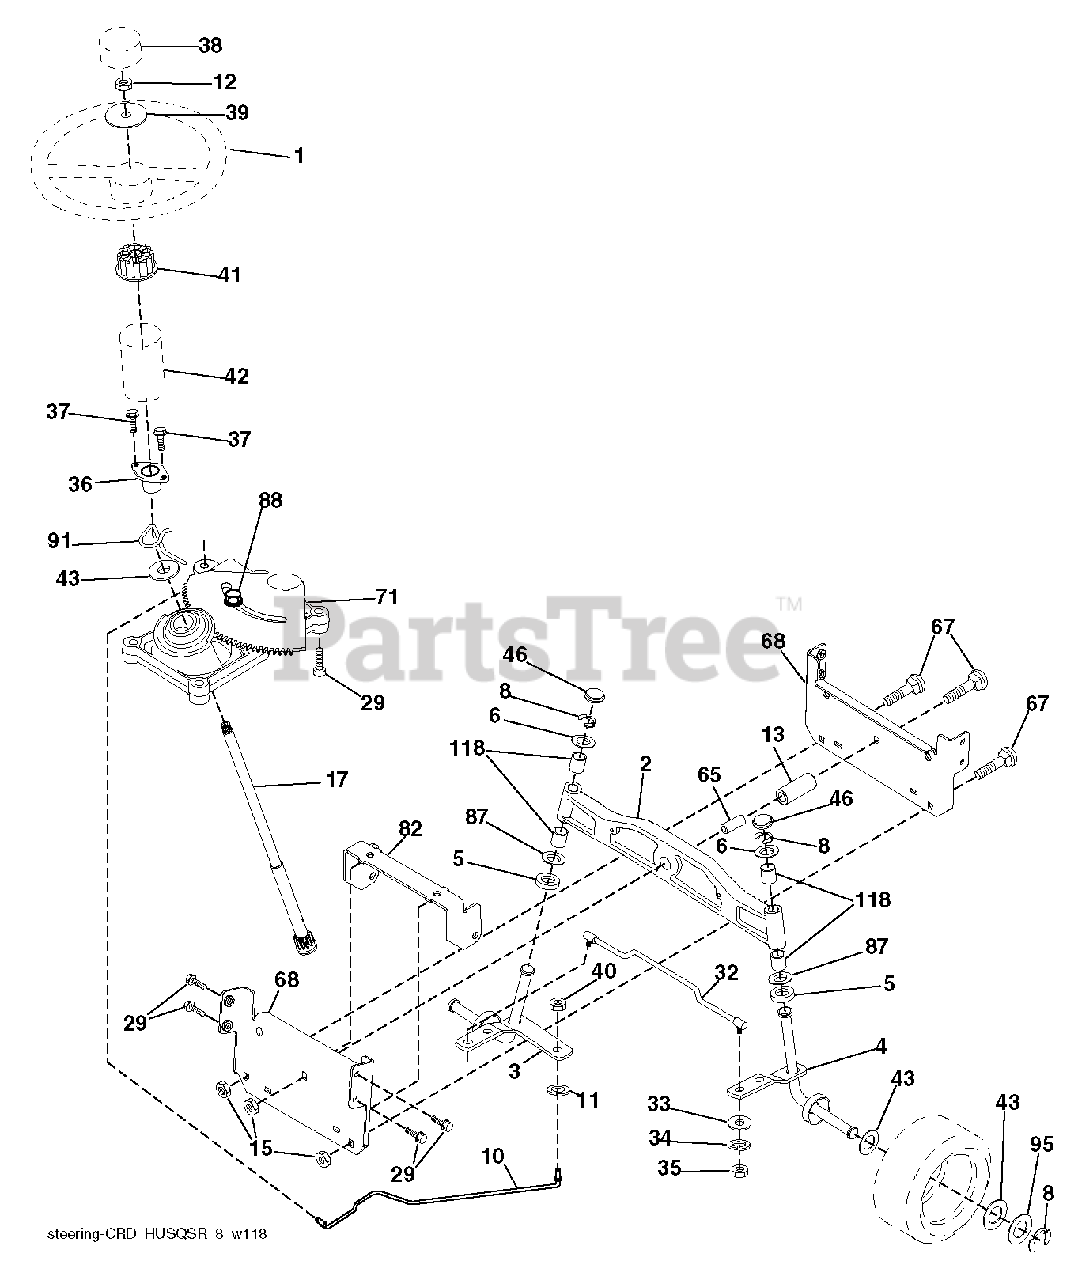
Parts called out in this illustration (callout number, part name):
1	WHEEL.STEERING.STDSRR.BLK/OV
2	AXLE.ASM.LT.CAST.LGHTWGHT
3	SPINDLE.ASM.LH.15"TIRES
4	SPINDLE.ASM.RH.15"TIRES
8	RING CLIP
10	DRAGLINK.15".TIRES.2001
11	WASHER, LOCK 3/8
12	NUT.HEX.1/2-20
13	TUBE, PIVOT AXLE
15	NUT LOCK FLG 3/8-16 UNC
17	SHAFT ASM STRG
29	SCREW, 3/8-16X3/4
33	WASHER M
34	LOCKWASHER
35	NUT, CROWNLOCK
36	BUSHING, STRG. BLK
38	CAP.WHL.STRNG.STDSRRD.SRS.BLK
39	WASHER 9/16"ID, 2 3/8"OD
40	NUT CROWNLOCK 3/8-24
41	ADAPTER, WHEEL STNG..
46	CAP.SPINDLE
65	SPACER.BRACE.AXLE
67	BOLT CARRIAGE
68	BRACE.AXLE.15"TIRES
71	STEERING ASM
82	BRACKET.SUSP.CHASSIS.FRONT.15
87	WASHER, FLAT .781 X 1 1/2"
88	BOLT, SHOULDER 7/16-20
91	CLIP.STEERING
95	WASHER.HARDENED
118	BUSHING, AXLE CAST
